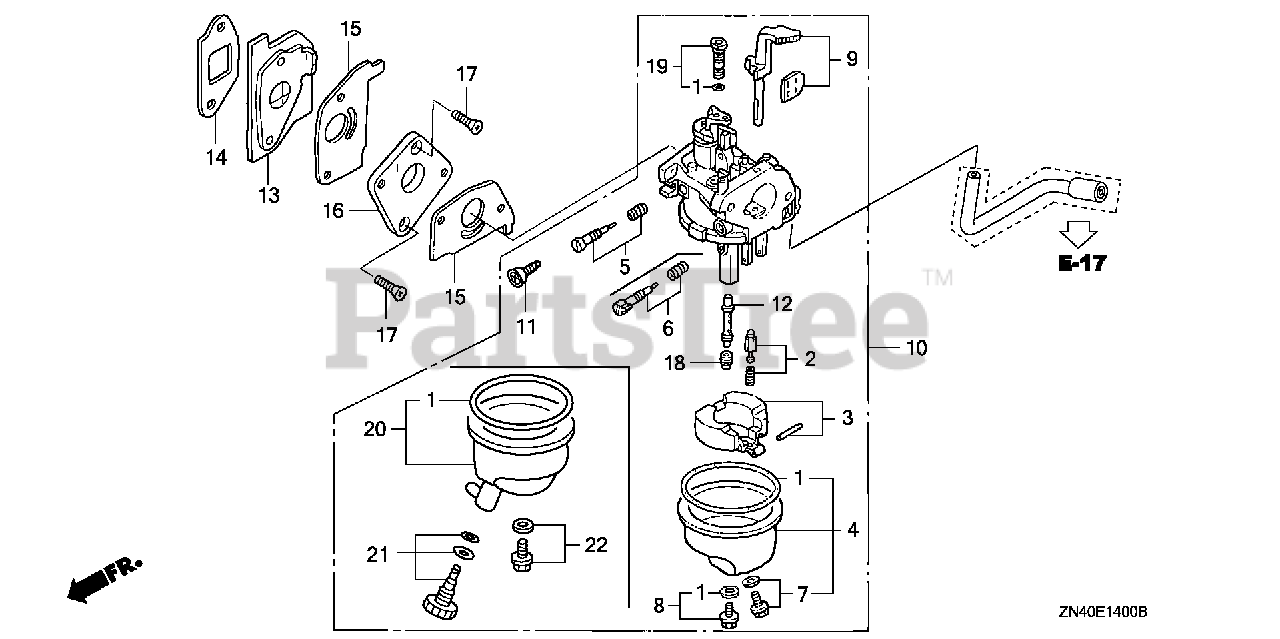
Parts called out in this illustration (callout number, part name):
1	GASKET SET
2	VALVE SET, FLOAT (SEAT NOT INCLUDED)
4	CHAMBER SET, FLOAT
6	SCREW SET, PILOT (CARBURETOR NO.)
7	SCREW SET, DRAIN
8	SCREW SET
10	CARBURETOR ASSY. (BF31D B)
10	CARBURETOR ASSY. (BF31D D)
11	SCREW, THROTTLE STOP
12	NOZZLE, MAIN (CARBURETOR NO.)
13	INSULATOR, CARBURETOR
14	GASKET, INSULATOR
15	GASKET, CARBURETOR
16	PLATE, CARBURETOR JOINT
17	SCREW, FLAT (5X20)
18	JET, MAIN (#50)
18	JET, MAIN (#55) (CARBURETOR NO.)
19	JET SET, PILOT (#35)
